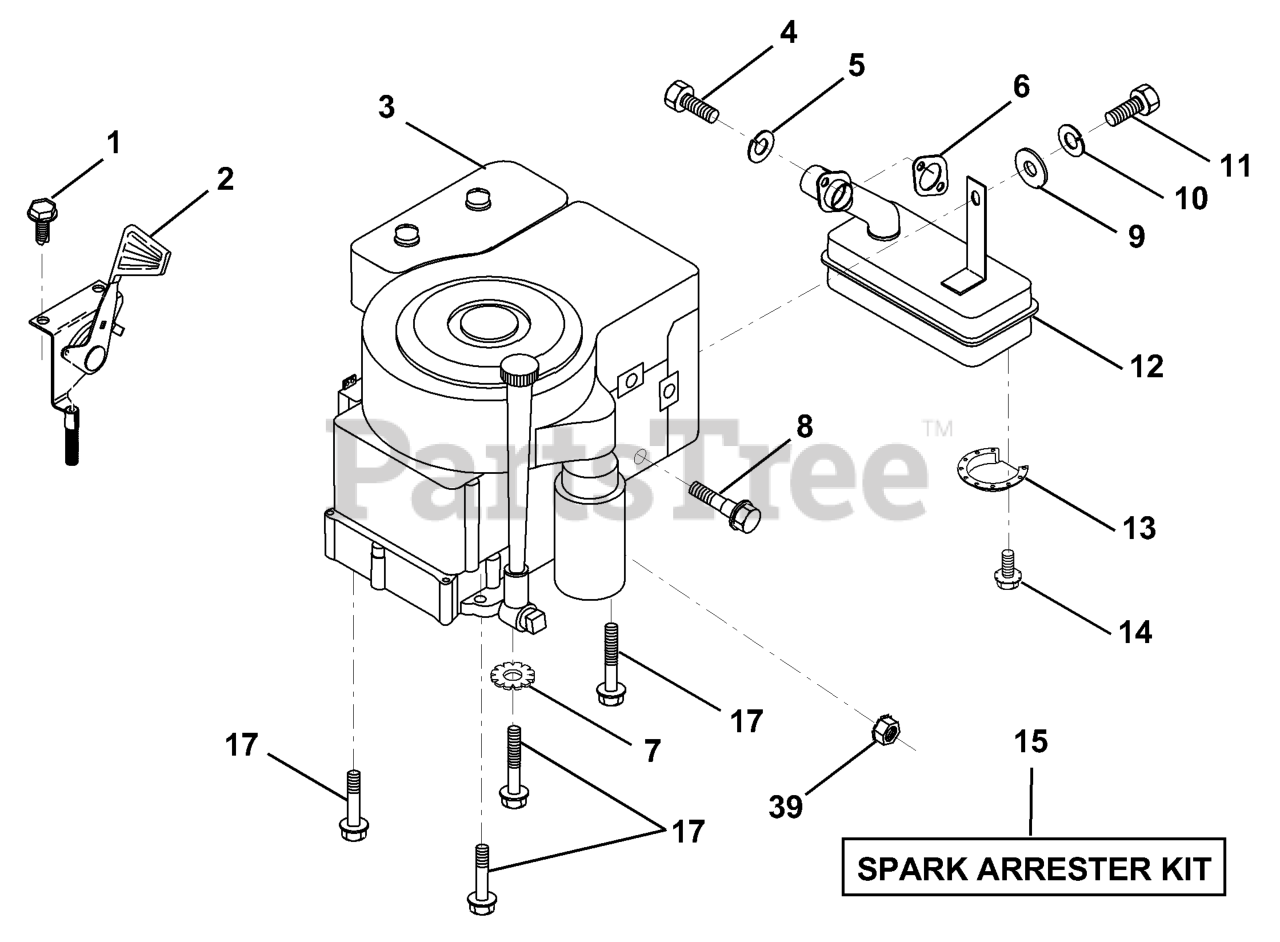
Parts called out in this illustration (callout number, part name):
2	CONTROL.TH/CH.RH.BLK.FLG.26
4	SCREW
5	WASHER.LOCK.HVY.HLCL.SPR.5/16
6	GASKET.ENG.1.313 ID.TIN PLATED
7	LOCKWASHER
9	WASHER
10	LOCKWASHER
11	Bolt, Hex Fin.
12	MUFFLER.SINGLE.B&S.12HP
13	DEFL MUFFLER LTV
14	SCREW
15	KIT.SPARK ARRESTOR 794945 B&S
17	SCREW LT
39	NUT FLANGE 1/4-20 STARTER NUT
